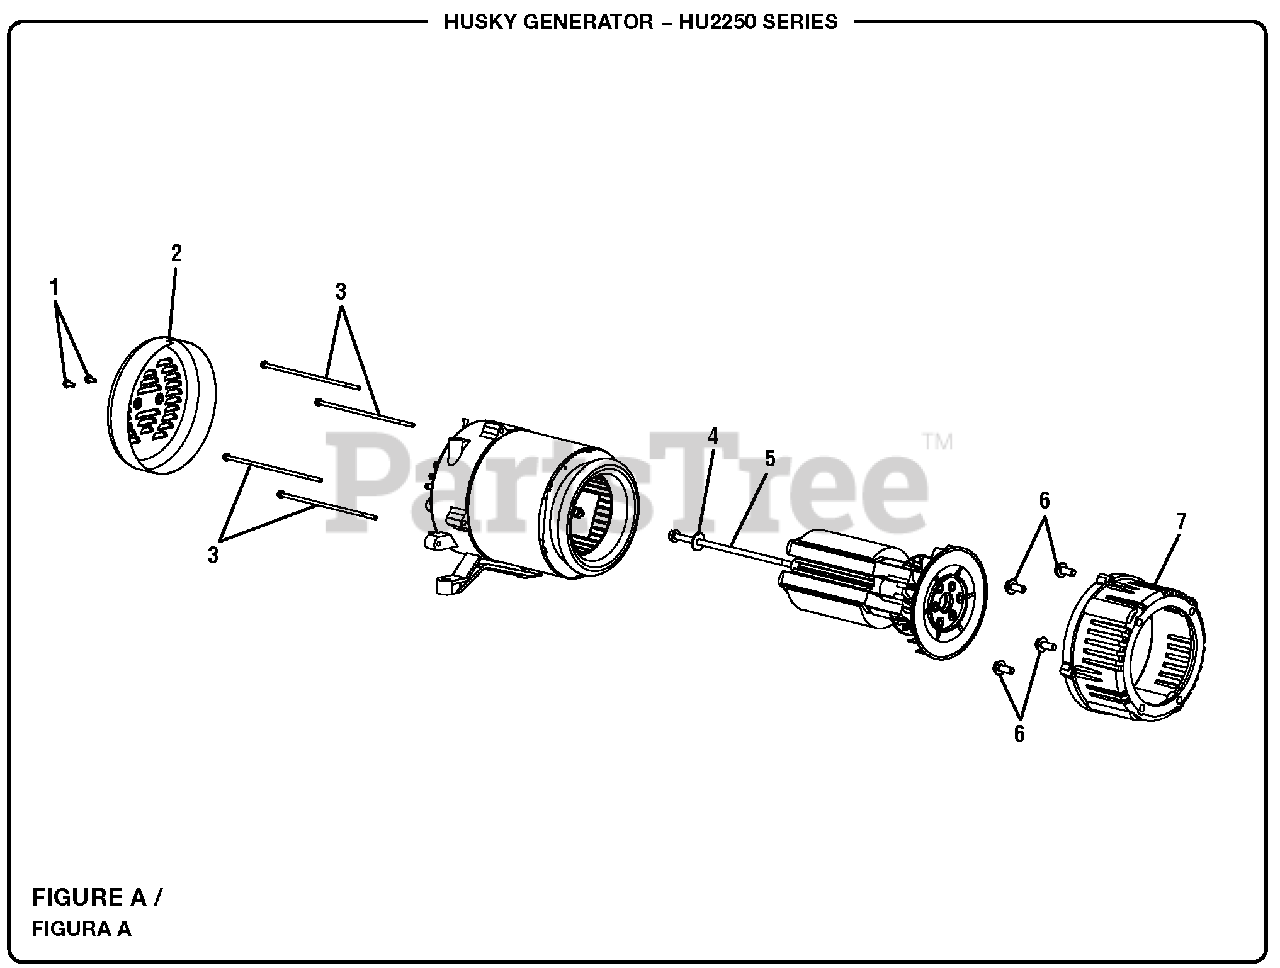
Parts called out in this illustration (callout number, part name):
2	Engine Cover
3	Bolt (1/4-20 x 6 in., Hex. Hd.)
4	Lock Washer (5/16 in.)
5	Bolt (5/16-24 x 6-5/8 in., Hex. Hd.)
6	Bolt (3/8-18 x 1-1/4 in.)
7	Engine Adapter
